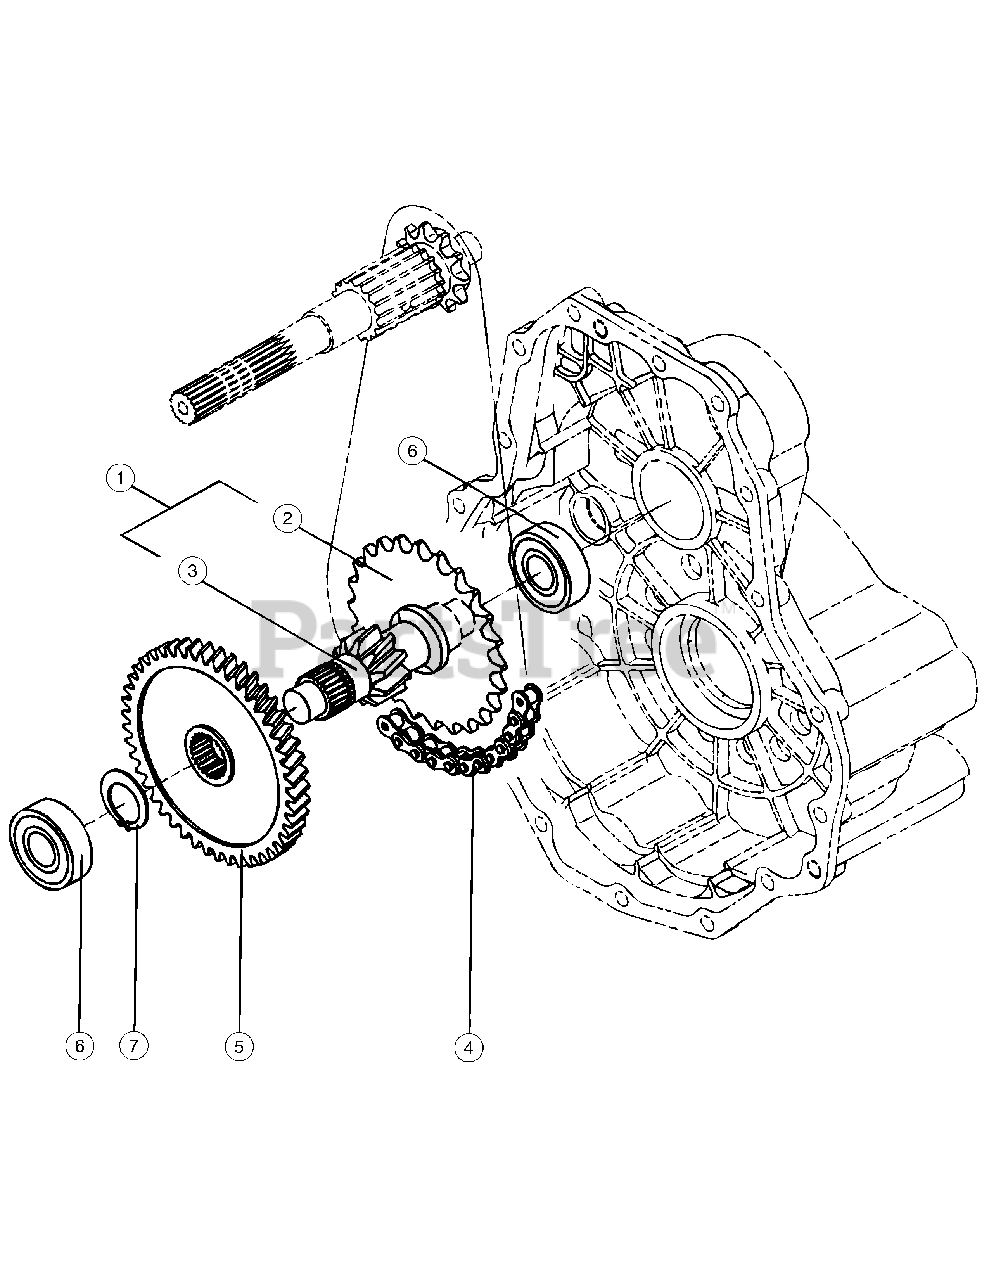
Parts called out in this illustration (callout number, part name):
1	Reduction Shaft Assembly
2	Sprocket, 27
3	Shaft, Reduction
4	Chain, 40 x 34
5	Gear, 46H, Reduction
6	Bearing, 6204R, SH2
7	Ring, 26
